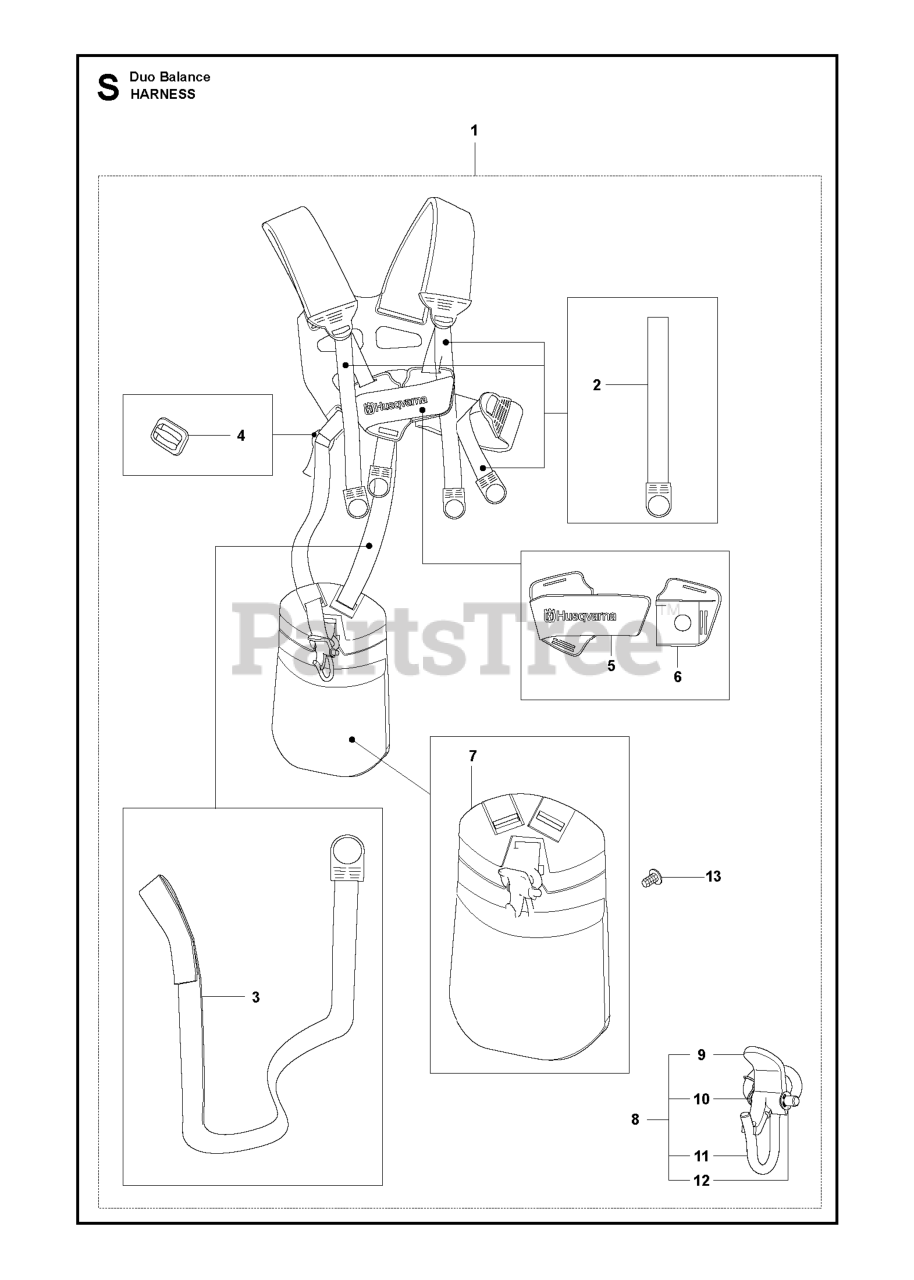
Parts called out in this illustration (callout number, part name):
8	DECAL WARNING (ENGLISH/FRENCH)
9	DECAL FENDER HUSQ
10	DECAL FENDER DANGER
14	DECAL V-BELT SCHEMATIC
20	DECAL BTRY SYMBOLS
